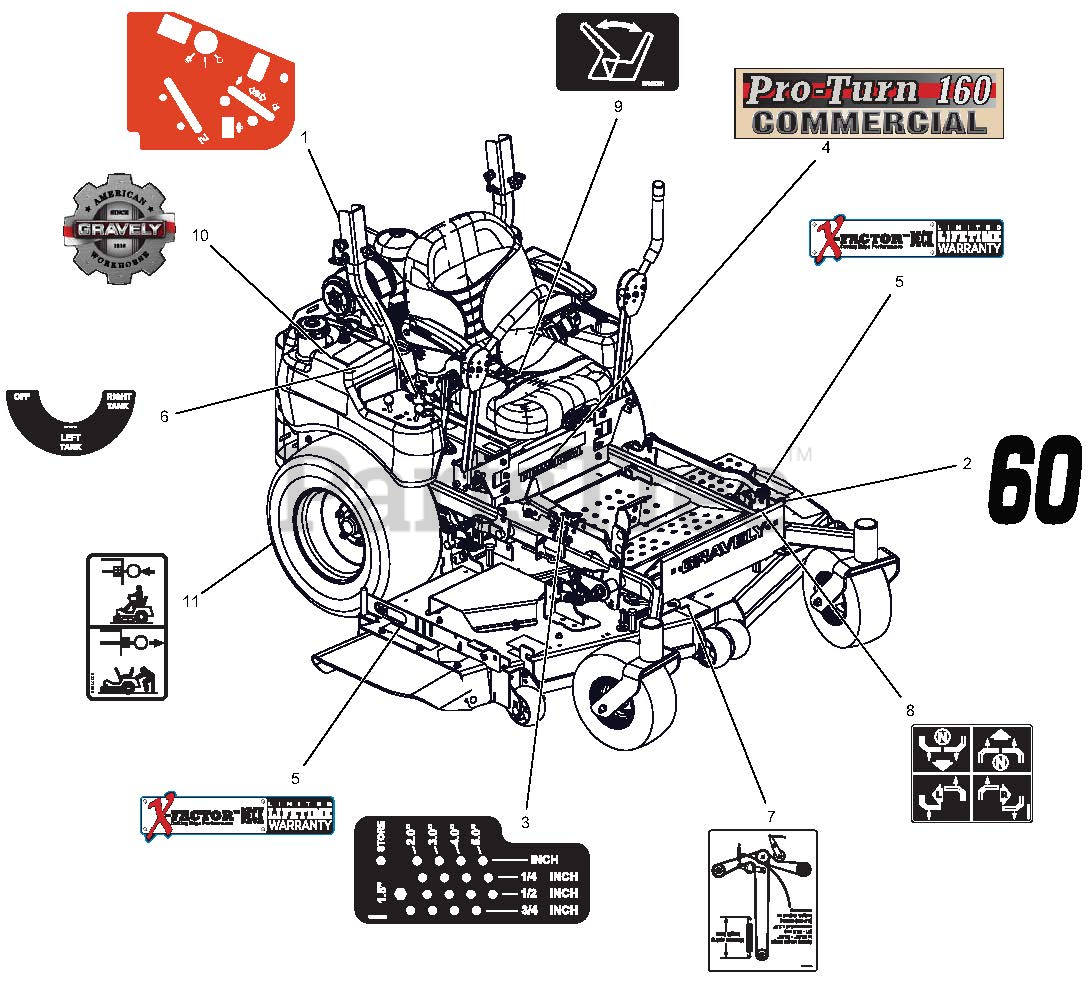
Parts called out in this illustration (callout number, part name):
1	PANEL, PT100 CONTROL
2	DECAL, 60"
3	DECAL, HEIGHT OF CUT
4	DECAL, PRO-TURN 160
5	DECAL, X-FACTOR DECK
6	DECAL, FUEL VALVE
7	DECAL, BELT DIAGRAM 60"
8	DECAL, INSTRUCTIONAL - STEERING
9	DECAL, SEAT RELEASE
10	DECAL, GRAVELY HERITAGE-LARGE
11	DECAL, TRANSMISSION DISCONNECT
